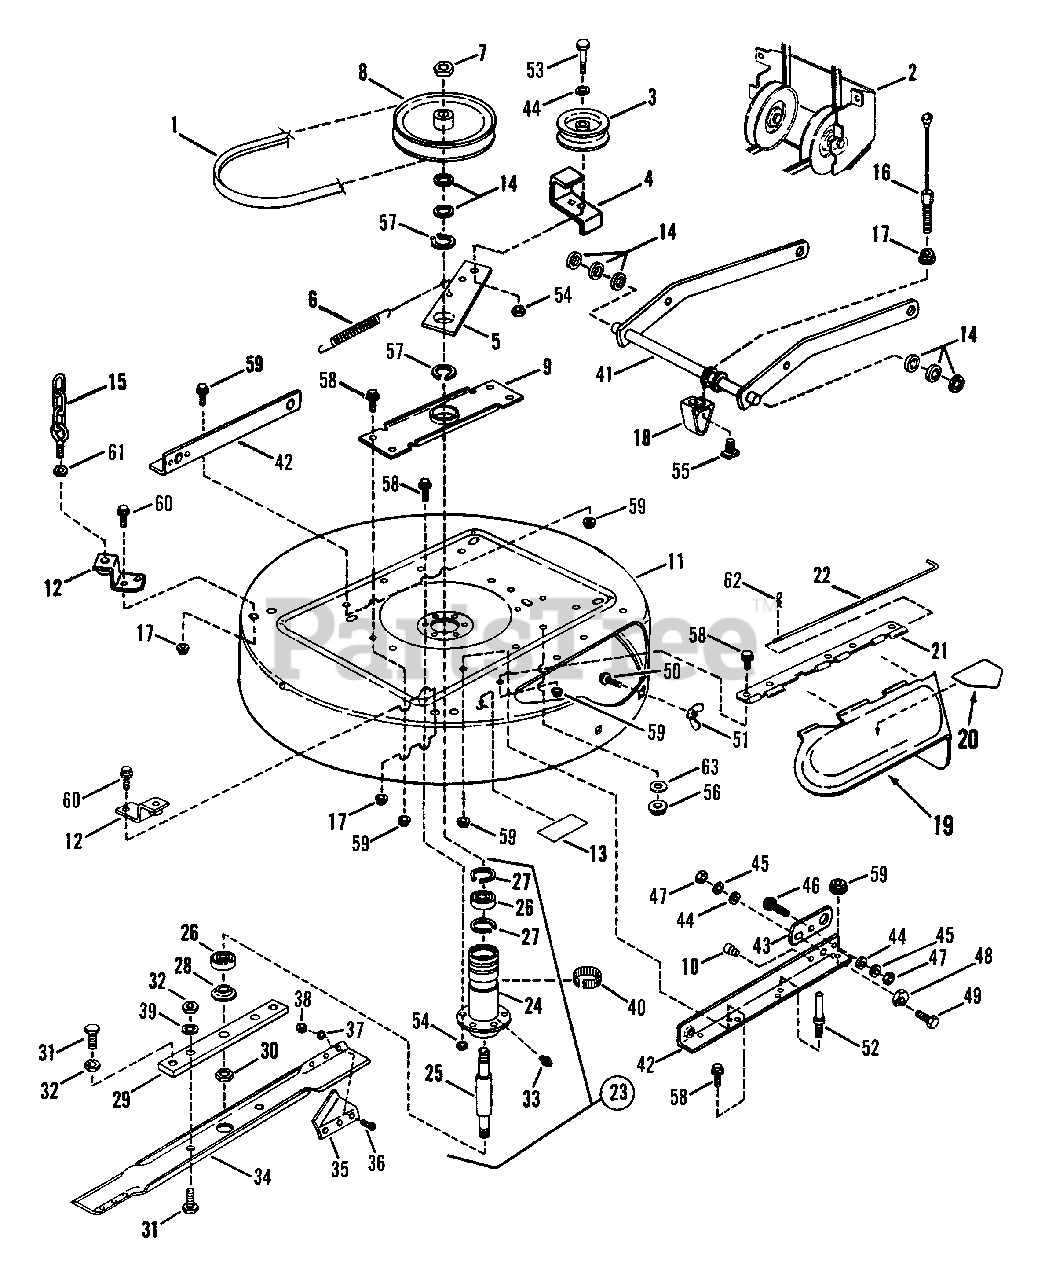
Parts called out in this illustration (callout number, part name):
1	BELT, 33" Mower Drive (A101)
2	ASSEMBLY, Mule Drive
3	PULLEY, Idler (Flat)(4.120.D.)
4	GUIDE, Belt
5	ARM, Idler
6	SPRING, Belt Tension
7	NUT, 3/4-16 Hex Jam
8	PULLEY, 8 O.D.
9	BRACE, Spindle
10	BUMPER BUTTON
11	DECK, 33" Cutter
12	ASY, Bracket Rear Lift
13	DECAL, Caution, (Deflector/Adapter)
14	WASHER, Shim
15	ASSEMBLY, 3/8 Bolt-Chain
16	CABLE, Front Lift (8.0")
16	CABLE, Front Lift (8.32")
17	NUT, 5/16 18 Hex Fl. Lock
18	BRACKET, Front Lift Hanger
19	DEFLECTOR
20	DECAL, Danger (Cut Finger)
21	HINGE, Side Chute
22	PIN, Hinge
23	ASSEMBLY, Spindle
24	HOUSING, Spindle
25	SPINDLE, 33" Mower (7.75")
26	BEARING, Spindle
27	RING, Retaining
28	WASHER, Spindle
29	HOLDER, Blade
30	NUT, 5/8-18 Hex Ctr. Lock
31	SCREW, 1/2-20 x 1" Hex Head Cap, Grade 5
32	NUT, 1/2-20 Hex Jam
33	FITTING, Lube (Press fit for .187 hole-no ball)
34	BLADE, 33" Cutter Deck
35	KIT, Air Lift
36	SCREW, 5/16-24 Machine
37	WASHER, 5/16 Internal Tooth Lock
38	NUT, 5/16-24 Hex
39	WASHER, 1/2" Internal Tooth Lock
40	RING, Tolerance
41	WELDMENT, Front Lift Arm
42	RAIL - 33"
43	LINK- ADJUSTMENT
44	WASHER, 3/8" Flat
45	WASHER, 3/8 Split Lock
46	3/8-16 BOLT, x 3/4" Carriage
47	NUT, 3/8-16 Hex
48	RING, Adjustment
49	SCREW, 3/8-16 x 1" HHC
50	BOLT, 5/16-18 x 3/4" Short Neck Carriage, Grade 5
51	WING-NUT, 5/16-18
52	STUD, Deck Stop
53	SCREW, 3/8-24 x 1-1/2" Hex Head Cap, Grade 2
54	NUT, 3/8-24 Hex Center Lock
55	T-NUT, 5/16-18
56	NUT, 3/8-24 Hex
57	RING, 2" External Retaining
58	BOLT, 3/8-16 x 3/4" Hex Flange Lock
59	NUT, 3/8-16 Hex Flange Lock
60	BOLT, 5/16-18 x 1/2" Hex Flange Lock, Grade 5
61	NUT, 3/8-16 Hex Jam
62	PIN, Hair Cotter
63	WASHER, 3/8 Int. Tooth Lock
